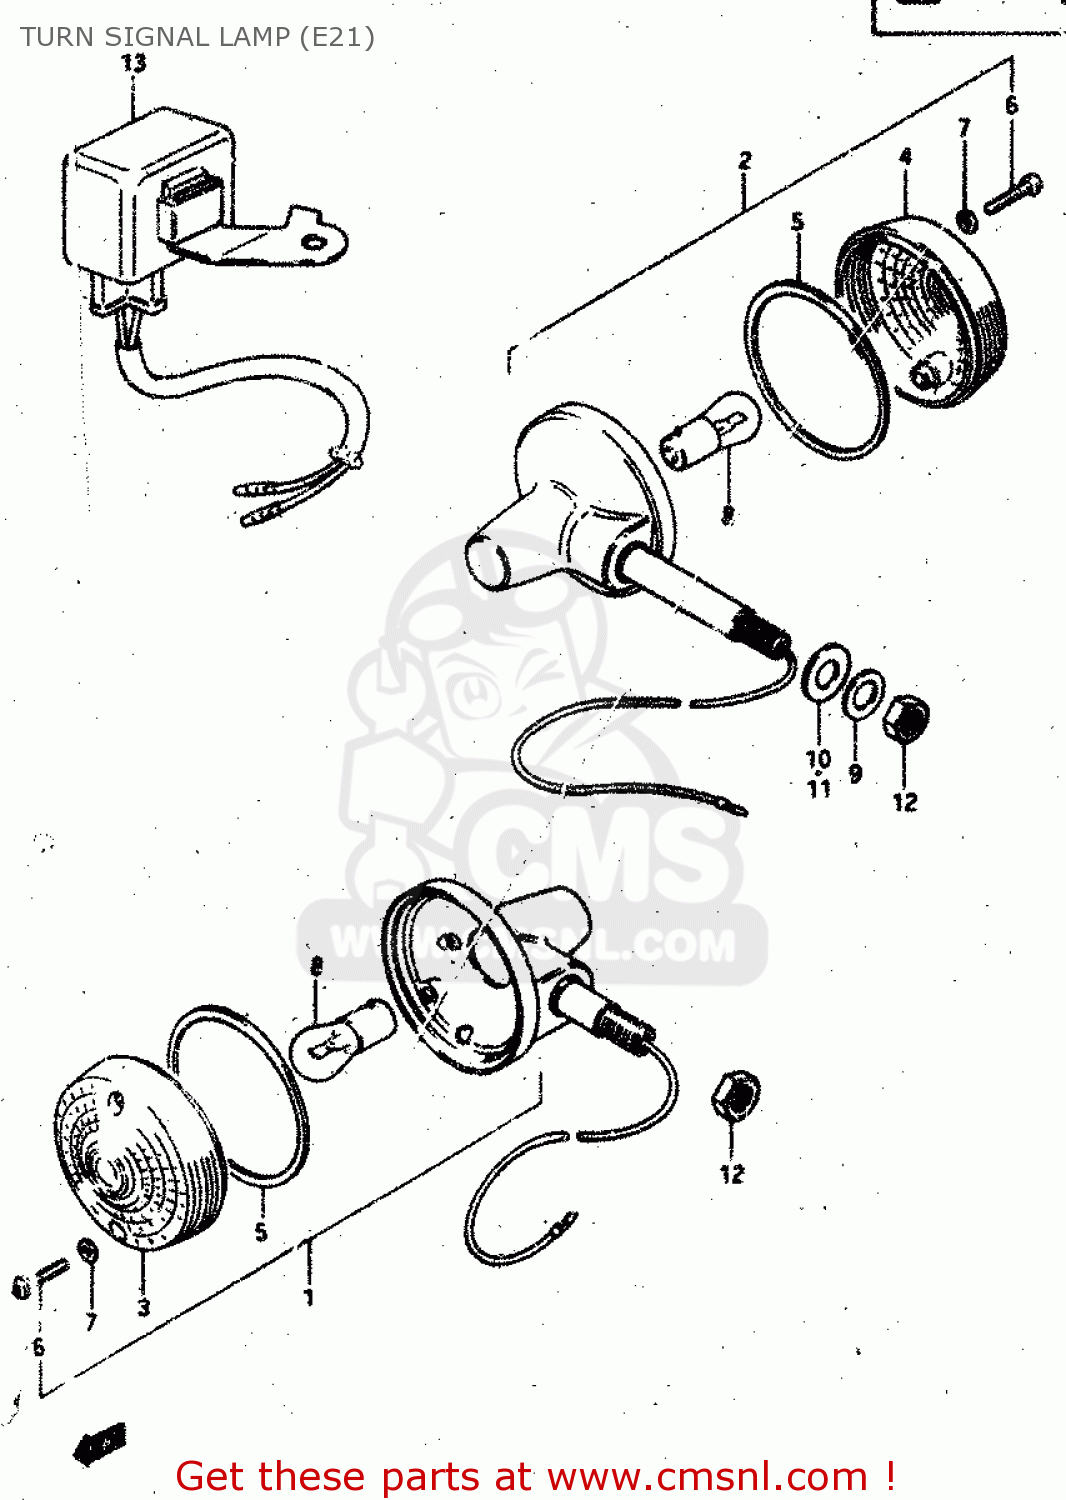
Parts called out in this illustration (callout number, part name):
1	LAMP, FRONT TURN SIGNAL
2	LAMP, REAR TURN SIGNAL
3	LENS
4	LENS
5	GASKET (NAS)
6	SCREW
7	GASKET (NAS)
8	BULB (6V,21W)
9	WASHER
10	WASHER(10.5X24X3.2)
11	WASHER (10.5X22X2.3)
12	NUT
13	RELAY, TURN SIGNAL
